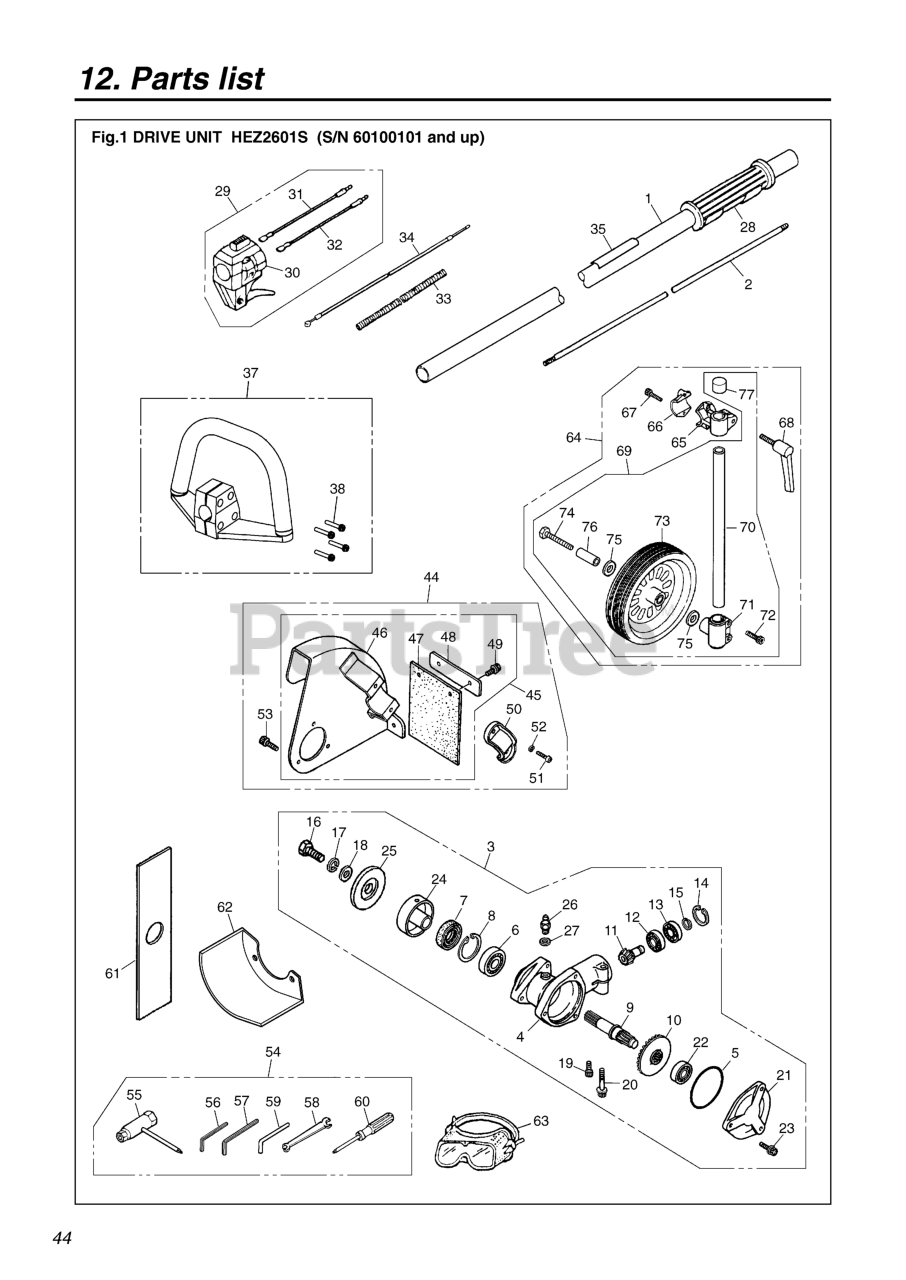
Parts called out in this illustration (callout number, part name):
1	PIPE COMP
2	SHAFT (RPLS -12212)
5	O-RING
7	SEAL, OIL
8	RING, SNAP, M32 x 1.2
9	SHAFT, GEAR
10	GEAR
11	PINION
12	BEARING (RPLS T3403-13530)
13	BEARING (RPLS T3300-13531)
14	RING, SNAP, M24 x 1.2
15	RING, SNAP (RPLS T3300-13330)
16	BOLT, LH
17	WASHER (RPLS 3180-13270)
18	WASHER, M8 x 2.3 (RPLS -20823)
19	BOLT, M5 x 12
20	BOLT, M6 x 1.35
21	COVER
22	BEARING (RPLS T3403-13510)
23	BOLT
24	HOLDER (A)
25	HOLDER (B)
26	FITTING, GREASE
27	WASHER, M6 X .8
28	GRIP
29	LEVER ASSY
30	LEVER
31	CORD (A), BLACK
32	CORD (B), RED
33	TUBE (RPLS 4900-72141)
34	CABLE (RPLS 5580-83100)
35	NAME-PLATE
37	HANDLE ASSY. (REPLACES -14001)
38	SCREW
45	COMP. GUARD
46	GUARD (RPLS 6367-24110)
47	PLATE (RUBBER)
48	PLATE (REPLACES -24130)
49	BOLT, M5 X 12
51	BOLT, M6 X 18
52	WASHER, M6 X 15
53	BOLT
55	SOCKET
56	WRENCH (TOOL)
57	WRENCH (TOOL)
58	SPANNER, 8 X 10 (RPLS 2540- )
59	BAR
60	SCREWDRIVER
61	BLADE, EDGER (RPLS 147315)
62	COVER (CAN USE 6367-96110)
63	GOGGLE
64	WHEEL ASSY COMP (RPLS -25000)
65	BRACKET
66	CAP, LOWER
67	BOLT, M5 X 22
68	LEVER
69	WHEEL ASSY (RPLS -25100)
70	PIPE
72	BOLT, M6 X 25
73	WHEEL
74	BOLT (REPLACES -81060)
75	WASHER, M10 x 1.6
76	SPACER, PIPE
77	CAP
